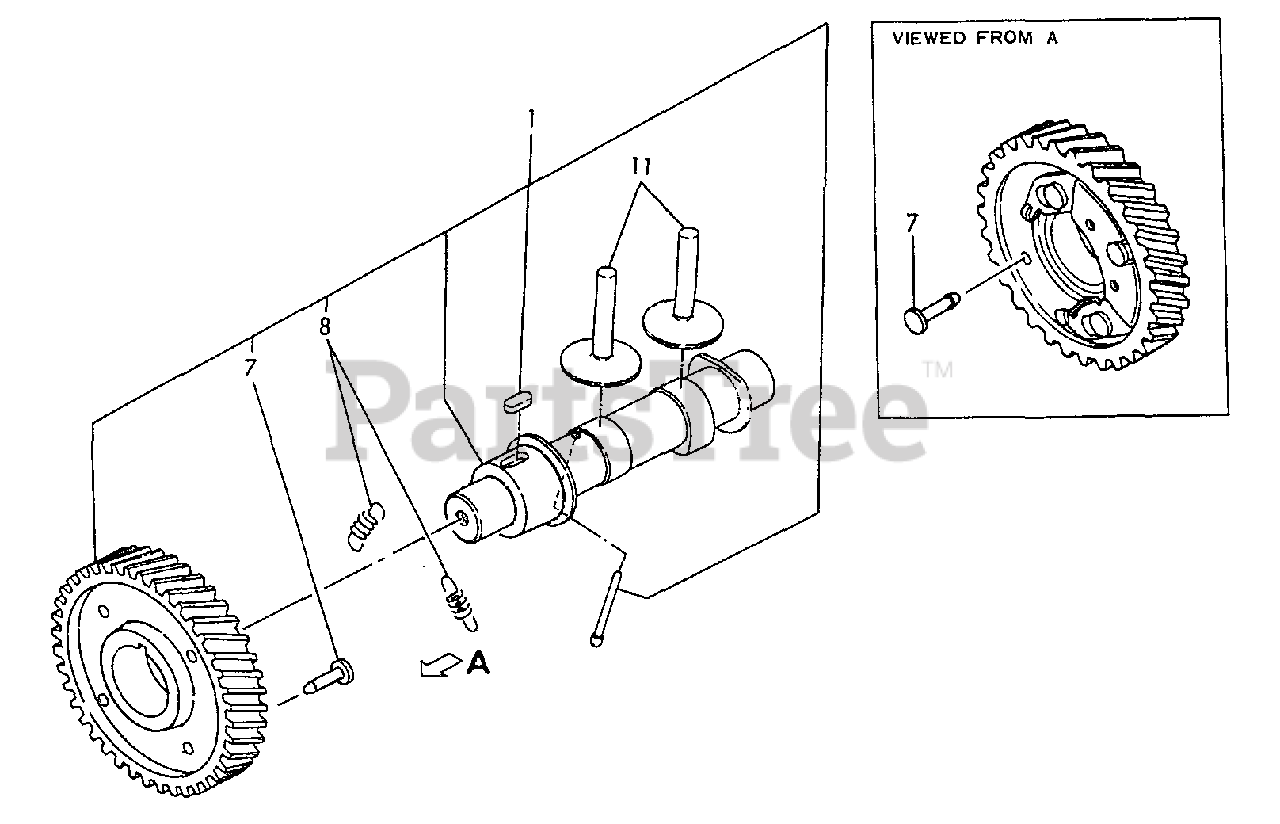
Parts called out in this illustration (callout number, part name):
1	CAMSHAFT ASSY
7	PIN, GUIDE - B
8	SPRING
11	TAPPET
